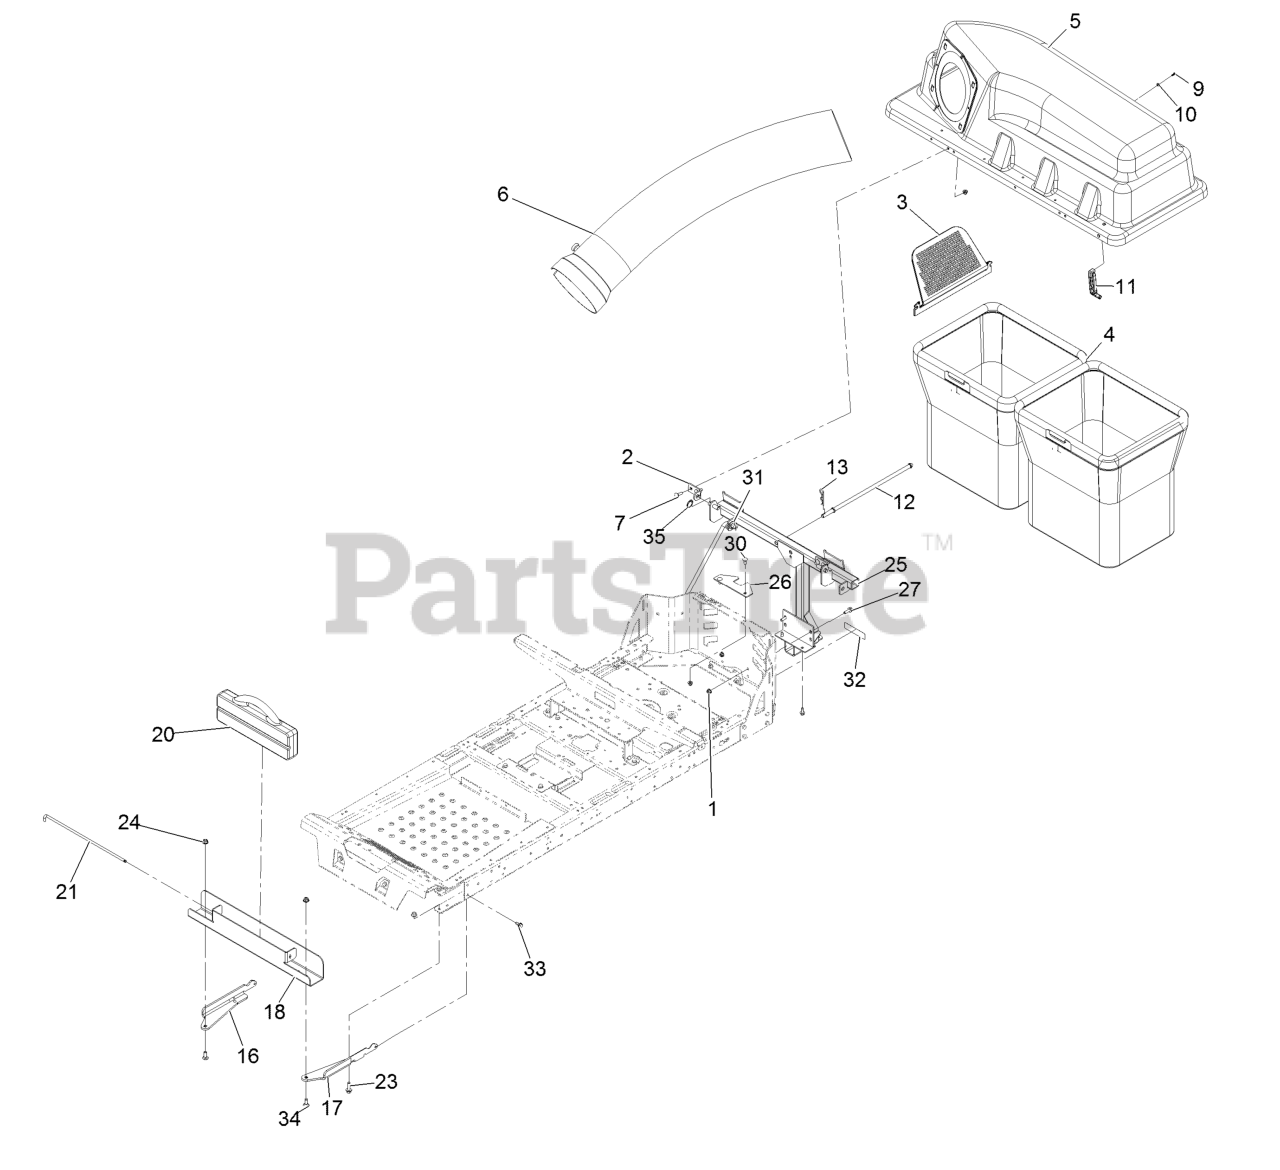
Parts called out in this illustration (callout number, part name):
1	Nut-Nyloc 5/16-18 Flg
2	Bracket-Pivot, Hopper
3	Screen-Bagger
4	Bag ASM
5	Bagger Top ASM
6	Tube-Bagger
7	Bolt-Carriage 5/16-18 X 1
9	Screw-Plastite
10	Washer-Flat
11	Latch-Rubber
12	Rod-Hood, Down (Hold)
13	Pin-Hair
16	Bracket-Weight, RH
17	Bracket-Weight, LH
18	Channel-Weight, Bagger
20	Weight-35 Pound
21	Pin-Weight
23	Screw-HHF
24	Nut-Nyloc 3/8-16 Flg
25	Frame-Pivot
26	Bracket-Stabilizer
27	Screw-HH Flg 5/16-18 X 1
30	Bolt-Carriage 5/16-18 X 3/4
31	Washer-1/2 SAE
33	Screw-HWH 5/16-18 X 3/4 Tf
34	Bolt-Carriage 3/8-16 X 1
35	Pin-Cotter, Circular
